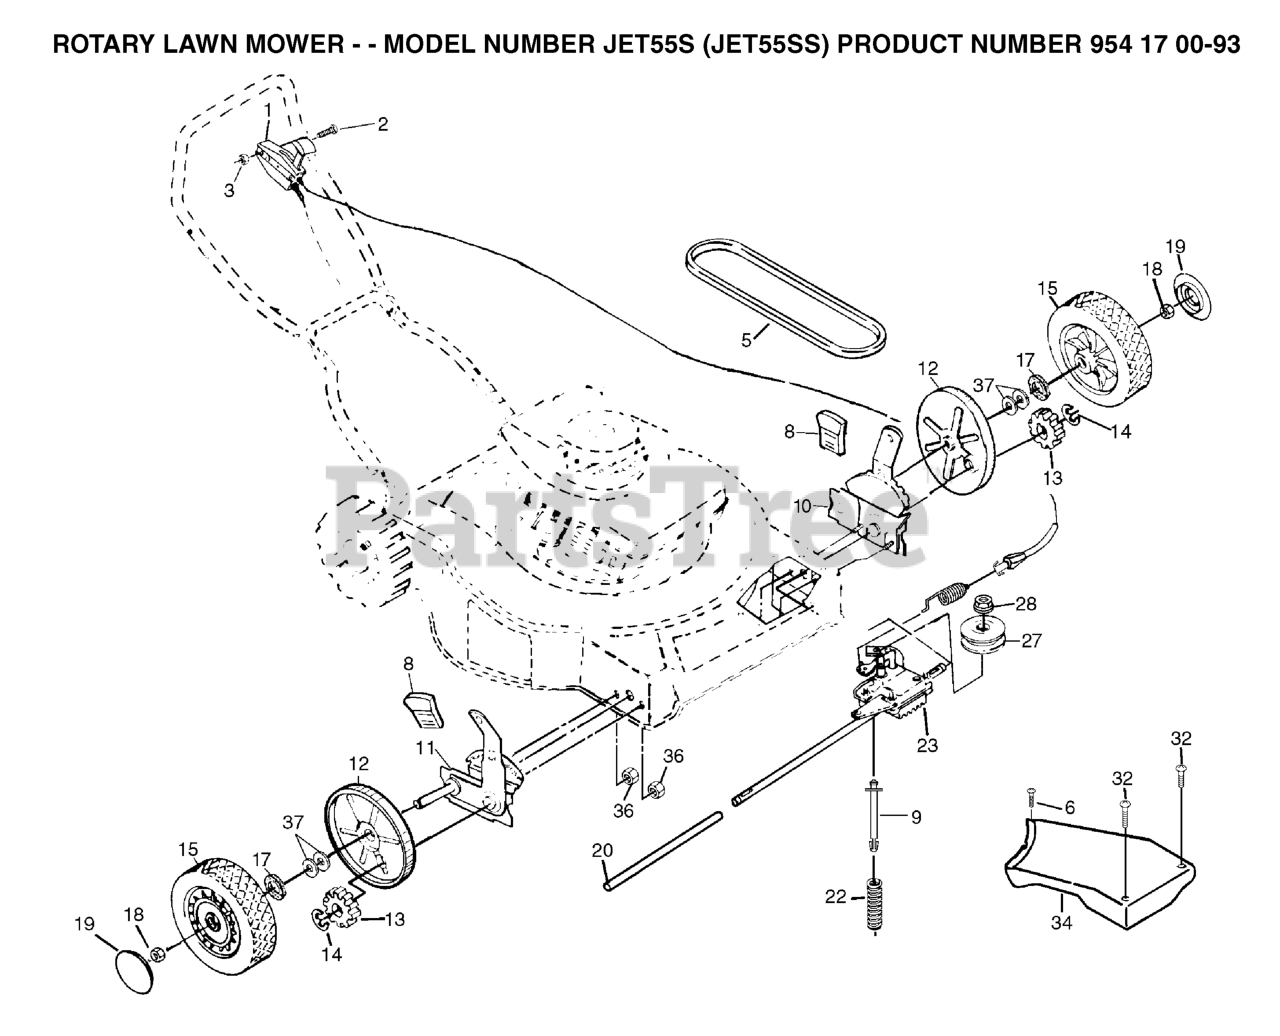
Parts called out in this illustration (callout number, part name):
1	DRIVE CONTROL 59.8 FWGD
2	SCREW.PAN.HEAD
3	LOCK NUT
5	BELT THERM .32
6	TAPPING SCREW
8	SELECTOR KNOB
9	SPRING RETAINER
10	WHEEL ADJUSTER ASSY (LEFT)
11	WHEEL ADJUSTER KIT RH
12	DUST COVER, WHEEL
13	PINION GEAR
14	E-RING 7/16 RE
15	RP WHEEL.8X2.RADIAL.GRAY
17	WASHER FLUT
18	HEX FLANGE LOCKNT
19	HUBCAP.8".GREY
20	DRV SHAFT TUBE PM
22	SPRING.EXTENSION
23	TRANSMISSION 22RD
27	PULLEY
28	FLANGED LOCKNUT 3/8-16 ZINC
34	COVER DRIVE
36	LOCKNUT.NYLOC.1/4-20
37	WAVE WASHER
